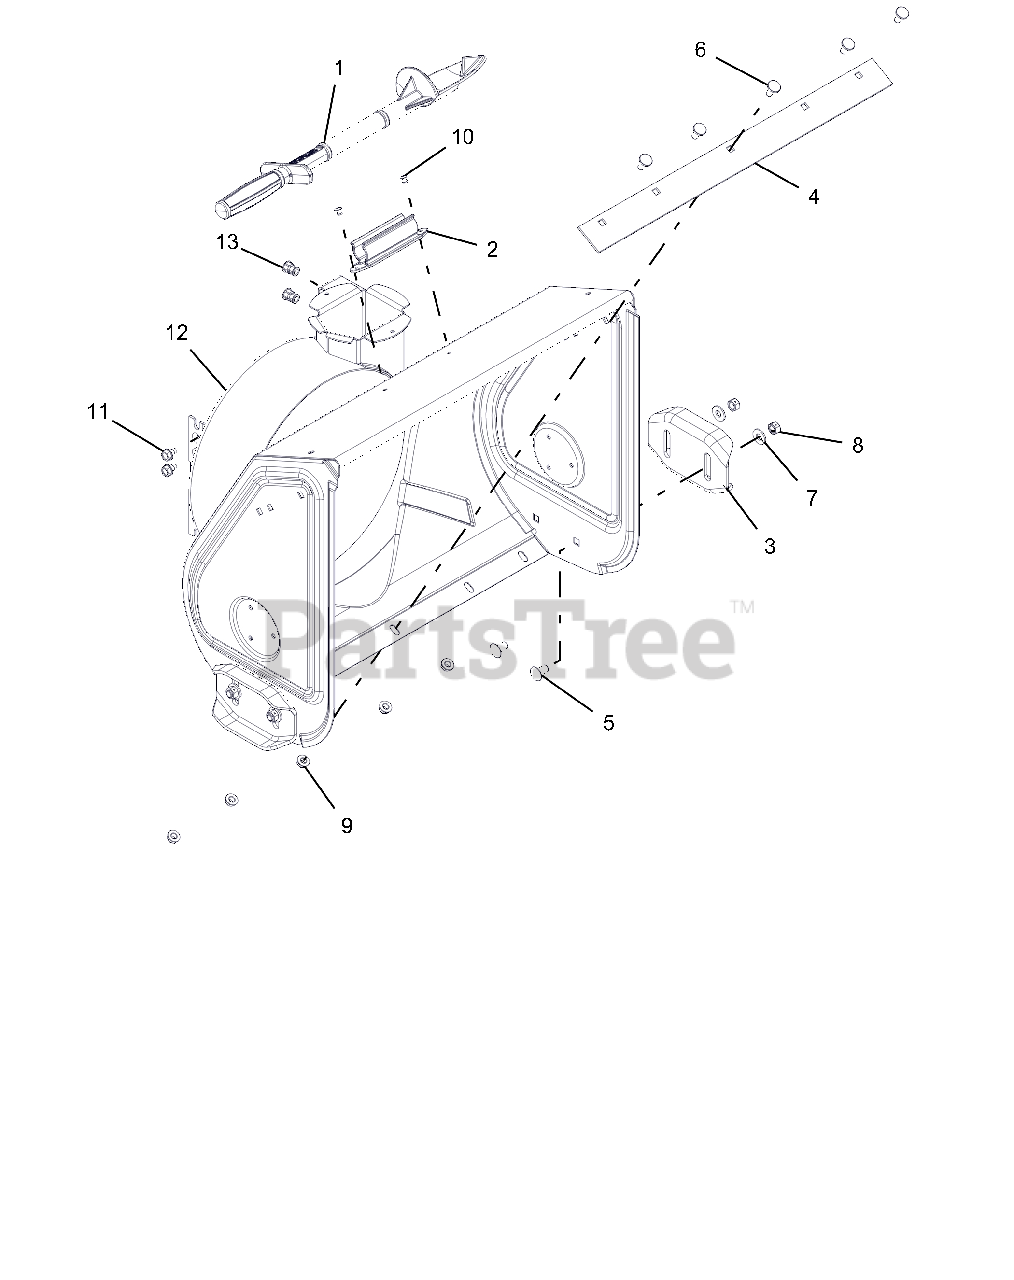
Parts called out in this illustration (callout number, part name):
1	DEVICE, SNOW CLEAN OUT
2	MOUNT, SNOW CLEAN OUT
3	SKID SHOE, REVERSIBLE - ORANGE
4	SCRAPER BLADE, 22" COMPACT
5	@BLT-RHDSSQNK .38-16X.75 G5YZ
6	BOLT, MODIFIED HEAD CARRIAGE
7	@WSHR-FL-STL.38X.875X.083 YWZC
8	@NUT-LK-CTR .38-16 YWZC
9	@NUT-LK-TOP-FLG .31-18 YWZC
10	RVT-POP .187 YZ
11	@SCR-TAP .31-18X.50 HWH TR YWZ
12	BLOWER HOUSING, 22" HI ORANGE
13	NUT, THREADED INSERT .38-16
